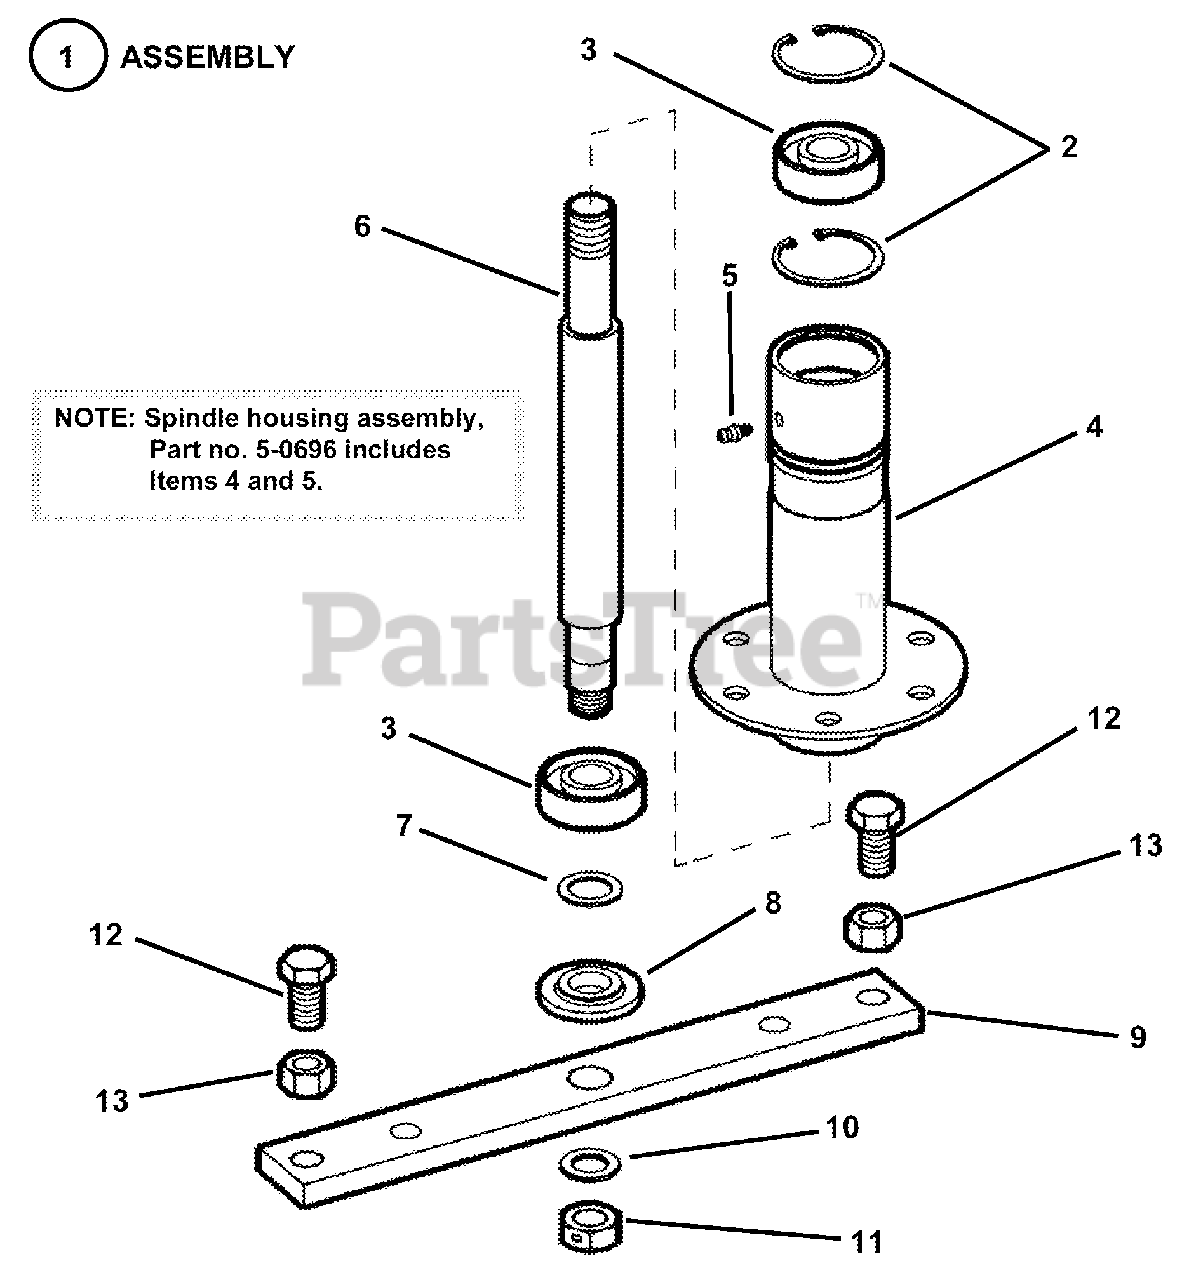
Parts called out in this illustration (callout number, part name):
1	ASSEMBLY, Spindle Housing
2	RING, 1.85" Internal Retaining
3	BEARING, Spindle
4	WELDMENT, Spindle Housing
5	FITTING, Lube (Press fit for .187 hole-no ball)
6	SPINDLE, Shaft (10.237" Long)
7	WASHER, 3/4" Shim
8	WASHER, Spindle
9	HOLDER, Blade
10	SPACER, Blade Centering
11	NUT, 5/8-18 Hex Center Lock
12	SCREW, 1/2-20 x 1-1/4" Hex Head Cap, Grade 5
13	NUT, 1/2-20 Hex Jam
